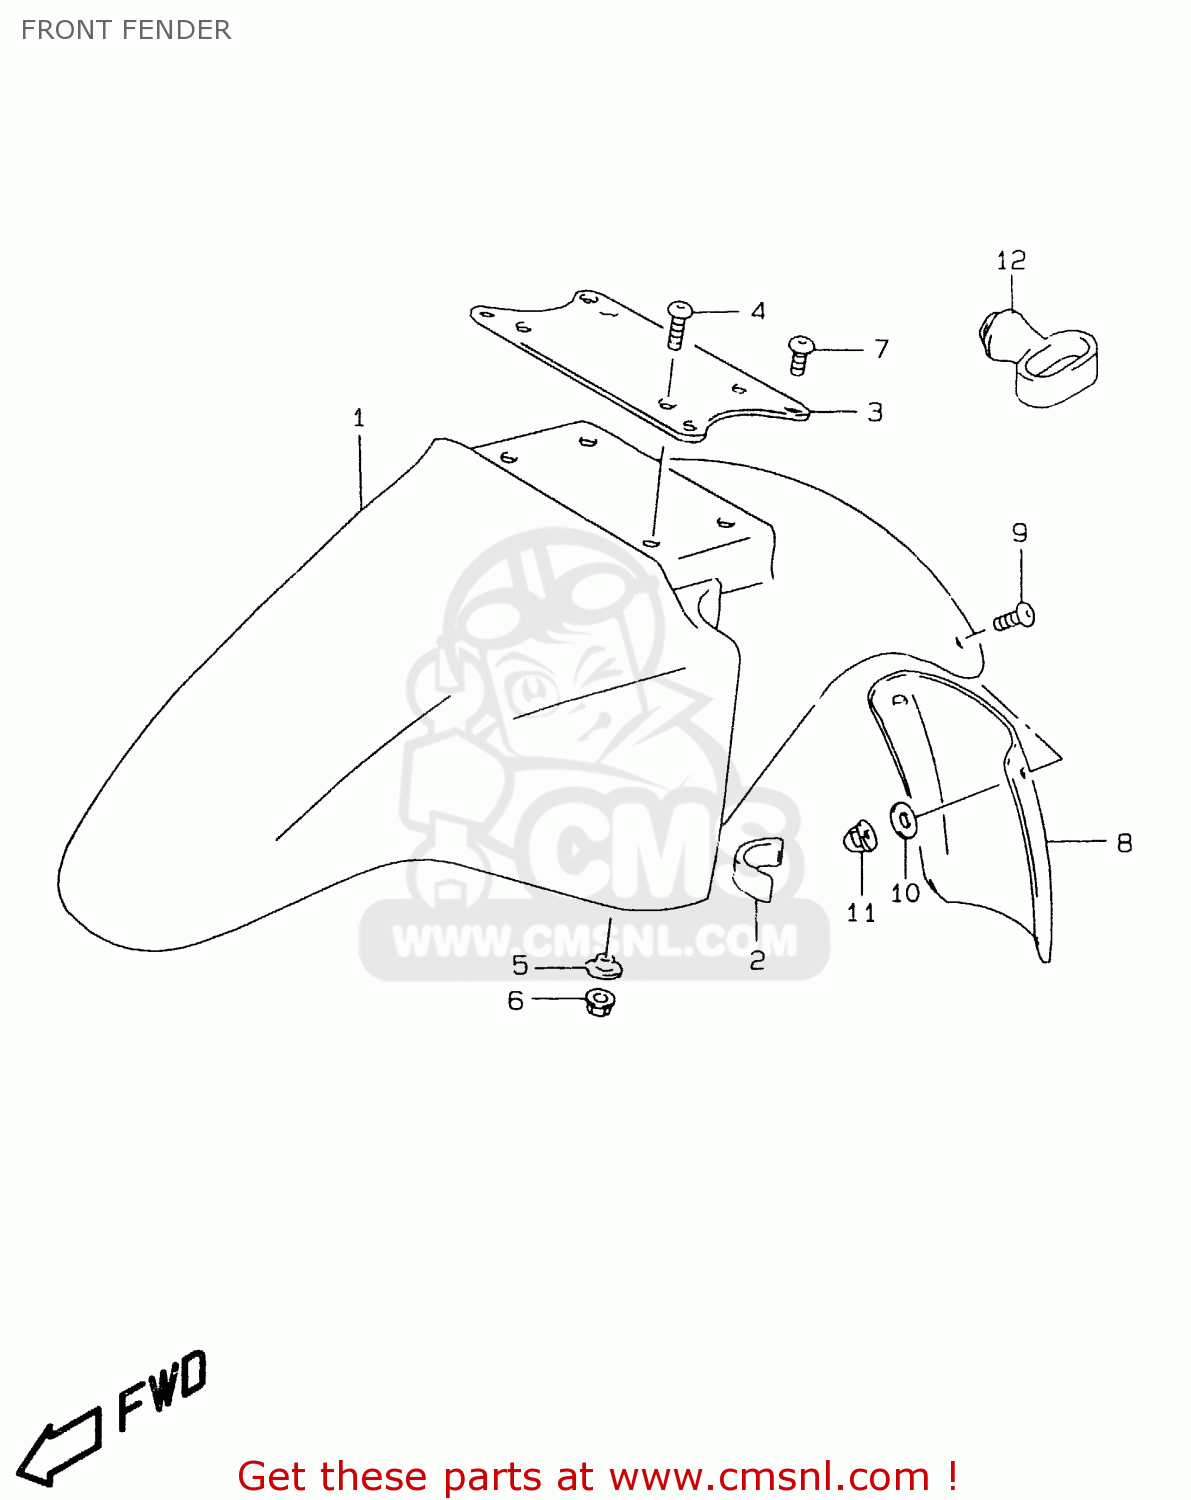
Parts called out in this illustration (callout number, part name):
1	FENDER,FRONT
2	CUSHION,FR FENDER
3	BRACE,FR FENDER
4	SCREW(5X16)
5	WASHER
6	NUT
7	SCREW(6X12)
8	MUDGUARD,FR FENDER
9	SCREW
10	WASHER(5.5X20X1.2)
11	NUT
12	GUIDE,CABLE
